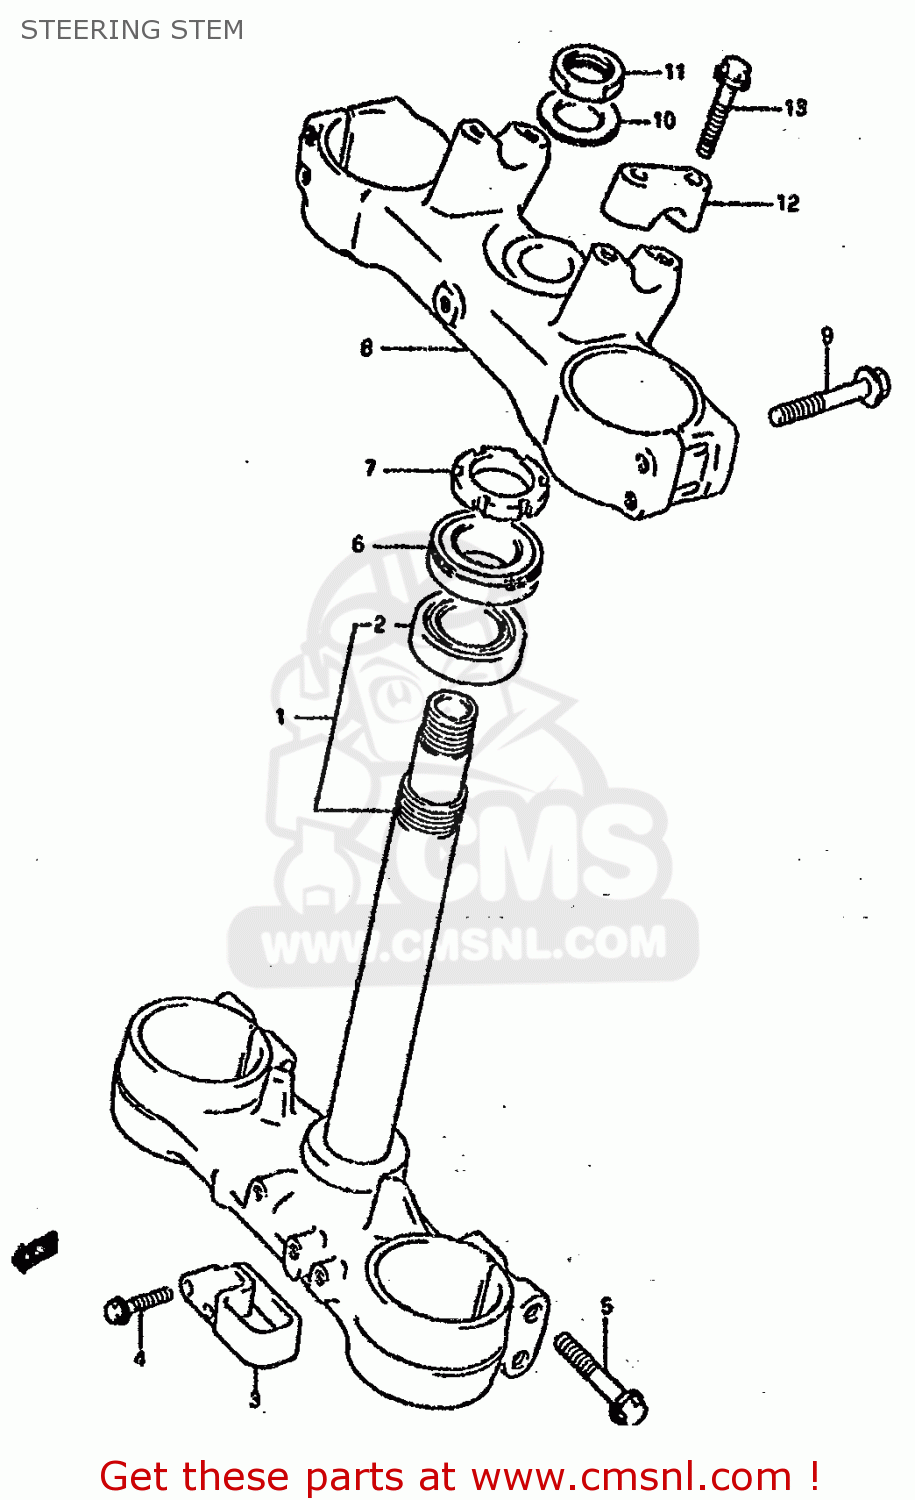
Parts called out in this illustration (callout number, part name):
1	STEM,STEERING
2	BEARING(30X52X16)
3	GUIDE,HOSE
4	BOLT
5	BOLT
6	BEARING(30X52X16)
7	NUT,STEERING
8	HEAD,STEERING STEM
9	BOLT
10	WASHER,STEM HEAD
11	NUT,STEM HEAD
12	NUT,STEM HEAD
13	BOLT
